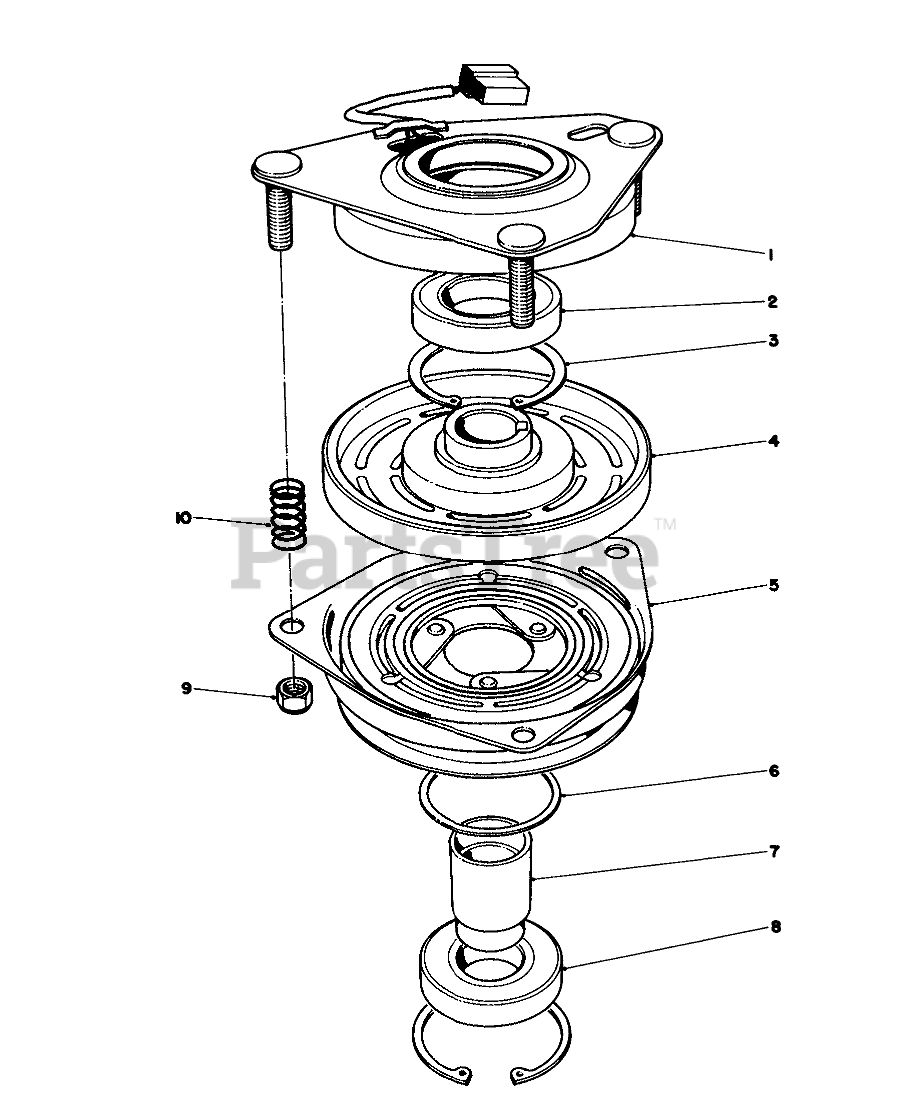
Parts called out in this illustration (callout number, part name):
1	Field Assembly (Incl. Ref. #2 & 3)
2	BEARING-FIELD
3	RING-RETAINING
4	Field Coil, Rotor & Bearing Assembly (Incl. Ref. #1)
5	Armature & Pulley Assembly (Incl. Ref. #3, 6, 7 & 8)
6	SPACER-BEARING, PULLEY
7	COLLAR-BEARING
8	BEARING-PULLEY
9	NUT-LOCK
10	SPRING
